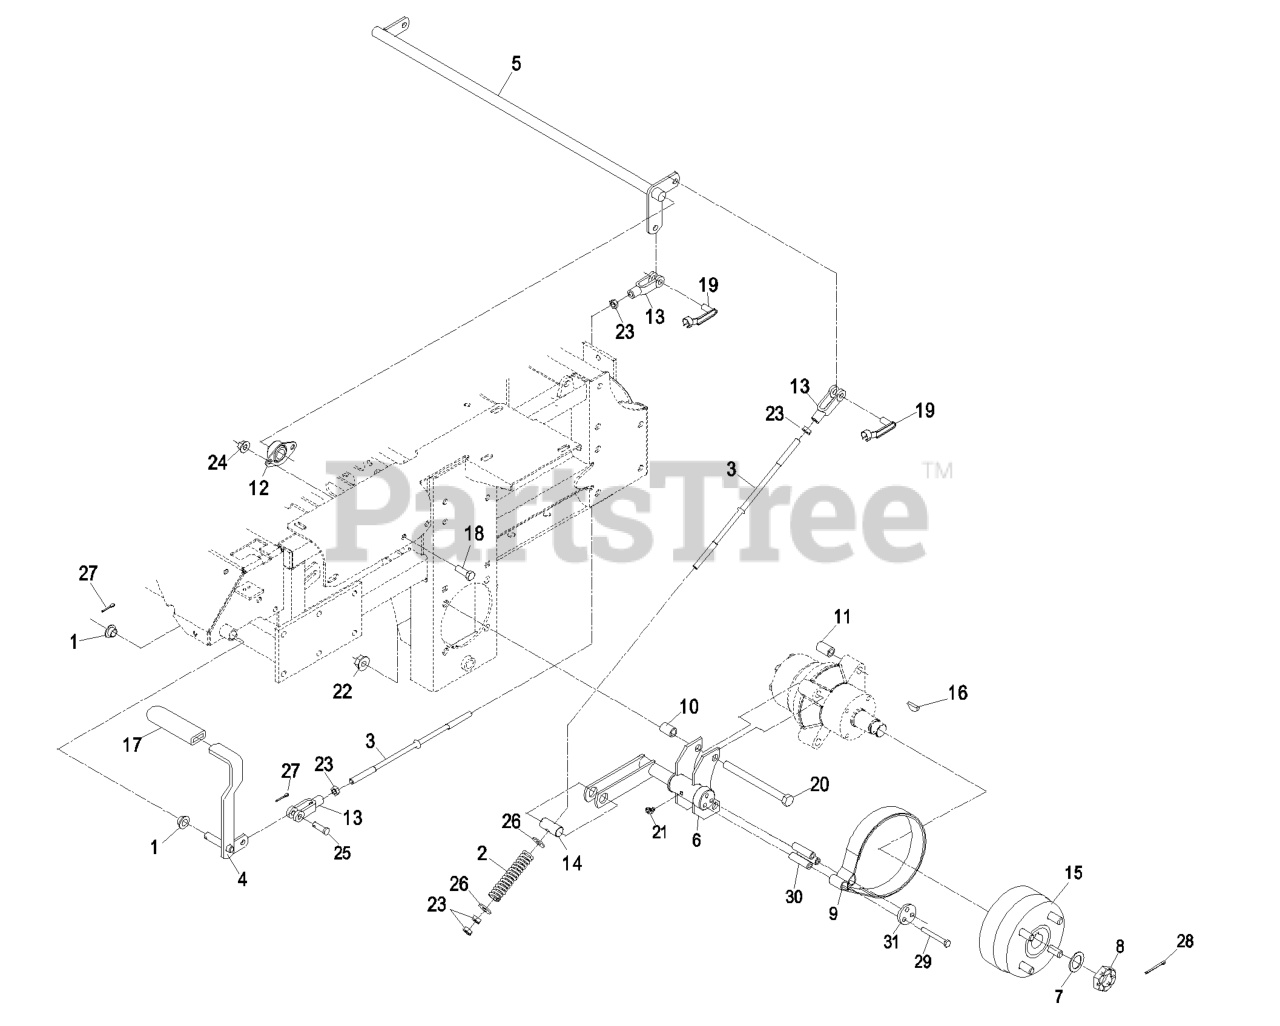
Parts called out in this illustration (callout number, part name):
1	BEARING-CONTROL
2	SPRING-BRAKE
3	ROD-BRAKE
4	BRAKE LEVER ASM
5	SHAFT-BRAKE
6	BRACKET-BRAKE
7	WASHER-SPACER
9	BAND,BRAKE
10	SPACER-WHEEL, SHORT
11	SPACER-WHEEL, LONG
12	BEARING-FLANGE, SIDE
13	YOKE-LINKAGE, BRAKE
14	PIN-TRUNION
15	WHEEL HUB ASM
16	KEY-WOODRUFF
17	GRIP-LEVER
18	SCREW-HH
19	PIN-SPRING, CLEVIS
20	SCREW-HH
21	FITTING-STRAIGHT
22	NUT-HHF
23	NUT-HEX
24	NUT-HHF, WHIZ
25	PIN-CLEVIS
26	WASHER-FLAT
27	PIN-COTTER
28	PIN-COTTER
29	SCREW-HH
31	RETAINER-BAND, BRAKE
